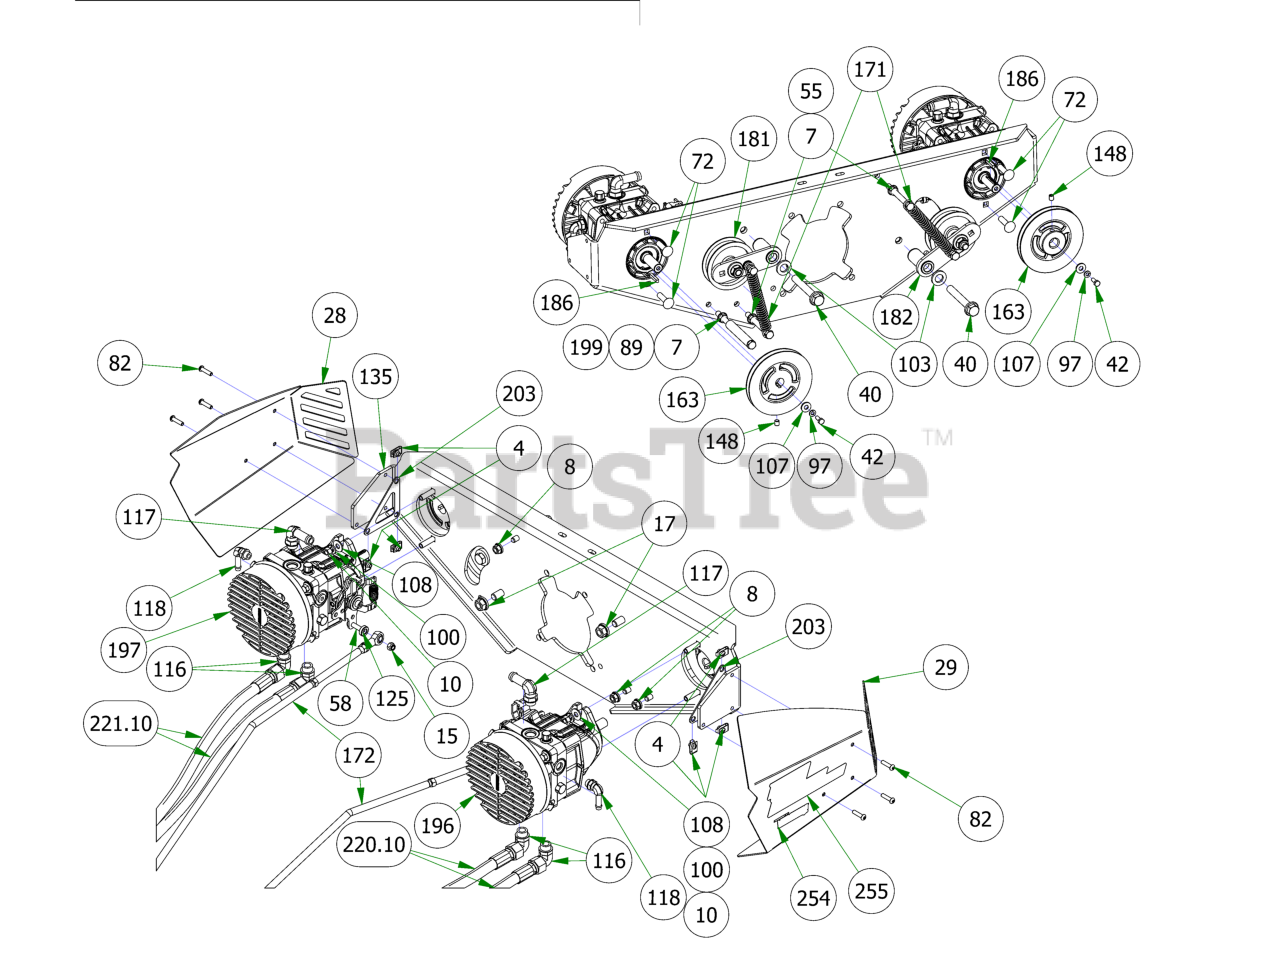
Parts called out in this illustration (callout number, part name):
4	1/4-20 Cage Nut
7	3/8-16 HEX SERRATED FLANGE NUT HARD/ZINC
8	3/8-16 NYLON INSERT FLANGE LOCKNUT (GR.F) ZINC
10	3/8-16 HEX NUT ZINC
15	5/16-18 NYL INS L/N ZC
17	1/2-13 NYLON INSERT FLANGE LOCKNUT ZINC
28	2019 Horizontal Pump Cover - Right - Black
29	2019 Horizontal Pump Cover - Left - Black
40	1/2-13 X 90MM HEX FLANGE BOLT W/SHOULDER (GR.8) ZINC
42	M6-1.0 X 16MM DIN 933 HEX TAP BOLT (CL 8.8) ZINC
55	3/8-16 X 3-1/2 HEX CAP SCREW (GR.5) ZINC
58	5/16-18 X 1-1/4 HEX C/S (GR.5) ZC
72	3/8-16 X 1-1/2 CARRIAGE BOLT ZINC
82	1/4-20 x 1" BS C/S 18-8 SS
89	3/8-16 X 5-1/2 HEX CAP SCREW (GR.5) ZINC
97	1/4 SPLIT LOCKWASHER ZINC
100	3/8 SPLIT LOCKWASHER ZINC
103	.635 ID X 1.120 OD X .140 THICK FLAT WASHER NYLON
107	1/4 USS FLAT WASHER (3/4 OD) ZINC
108	5/16 USS FLAT WASHER (7/8 OD) ZINC
116	2019 Outlaw 90 Degree Pump Fitting #6801-10-08
117	90 Degree Fitting, 1/2 x 3/4, 4601-8-8
118	90 Degree Fitting, 3/8 s 9/16
125	ACS Spacer 3/4x3/8x1/4
135	Pump Plate - 2019 Horizontal Gas
148	5/16-24 X 3/8 SOCKET SET SCREW (KNURLED CUP PT) PLAIN
163	5" Pump Pulley
171	ZT and ACS Handle Spring
172	2019 Renegade Push Rod Assembly
181	2019 Renegade Belt Tensioner LH
182	2019 Renegade Pump Belt Tensioner RH
186	5MM X 32MM SQ MACHINERY KEY 1018 STL (BOTH ENDS ROUND) PLAIN
196	2019 Rogue/Renegade Left Pump 16cc
197	2019 Outlaw Renegade Right Pump 16cc
199	3/8 hose 4" long
203	Pump Plate Clip Nut Holder
220.10	2019 Renegade Hydro Hose
221.10	2019 Renegade Hydro Hose
254	2022 Powered By Vanguard Decal
255	993cc-EFI Backplate Cluster
